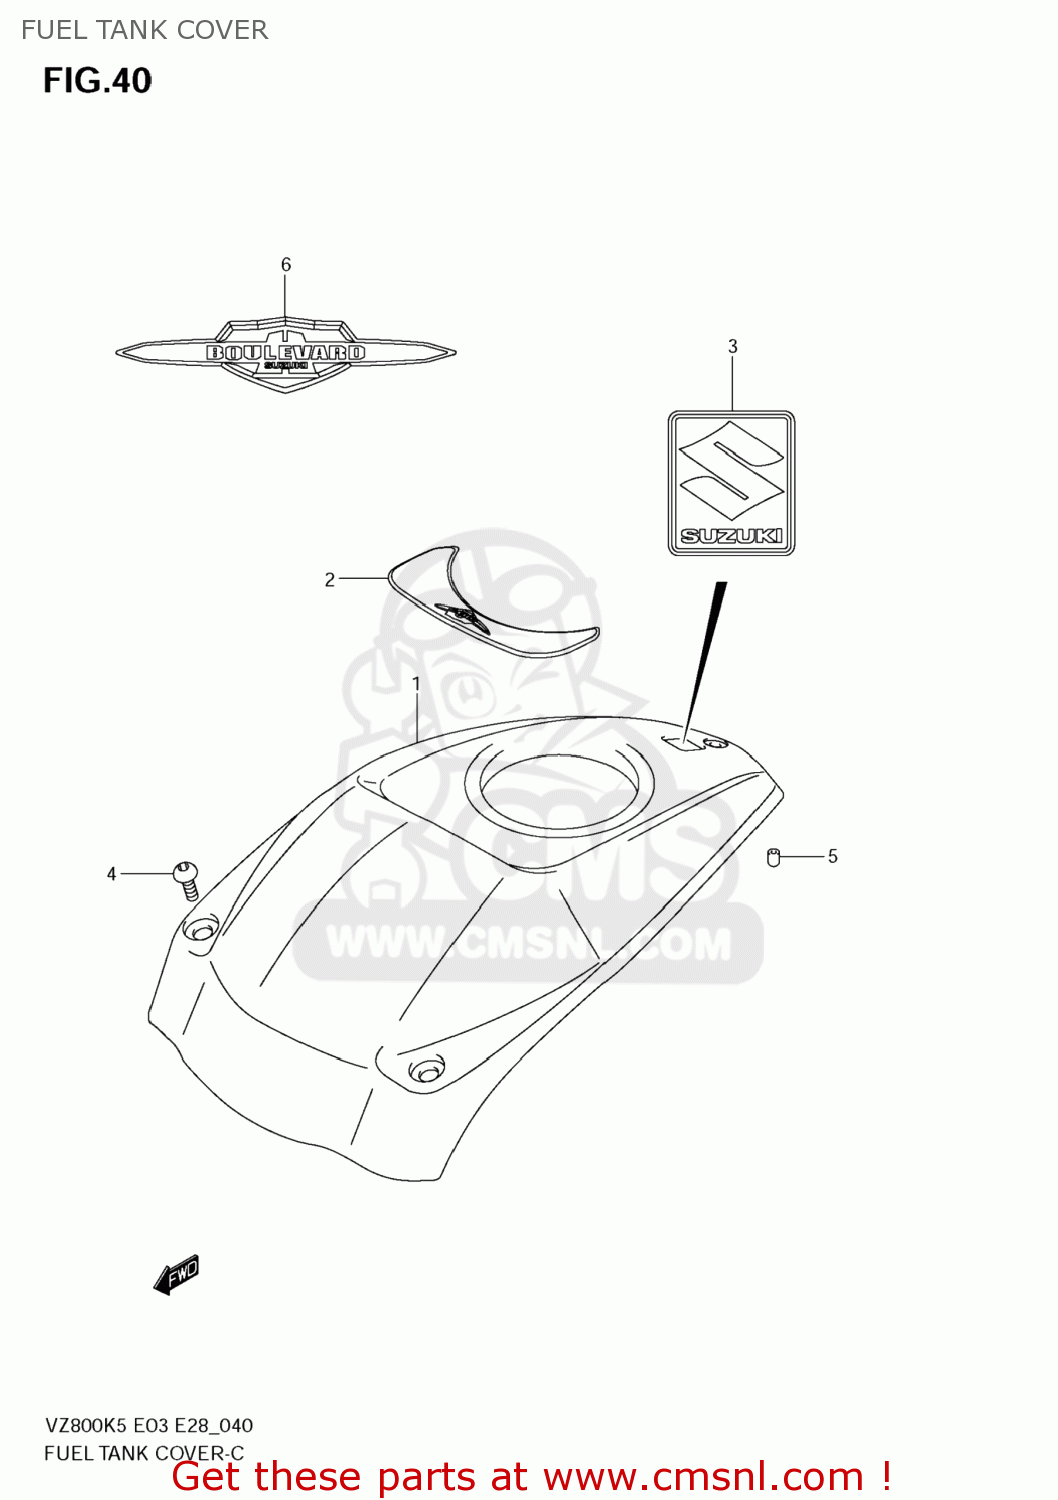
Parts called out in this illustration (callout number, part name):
1	COVER,FUEL TANK UPR
2	EMBLEM,FUEL TANK COVER
3	EMBLEM,S
4	SCREW(5X13)
5	CUSHION
6	EMBLEM,BOULEVARD
